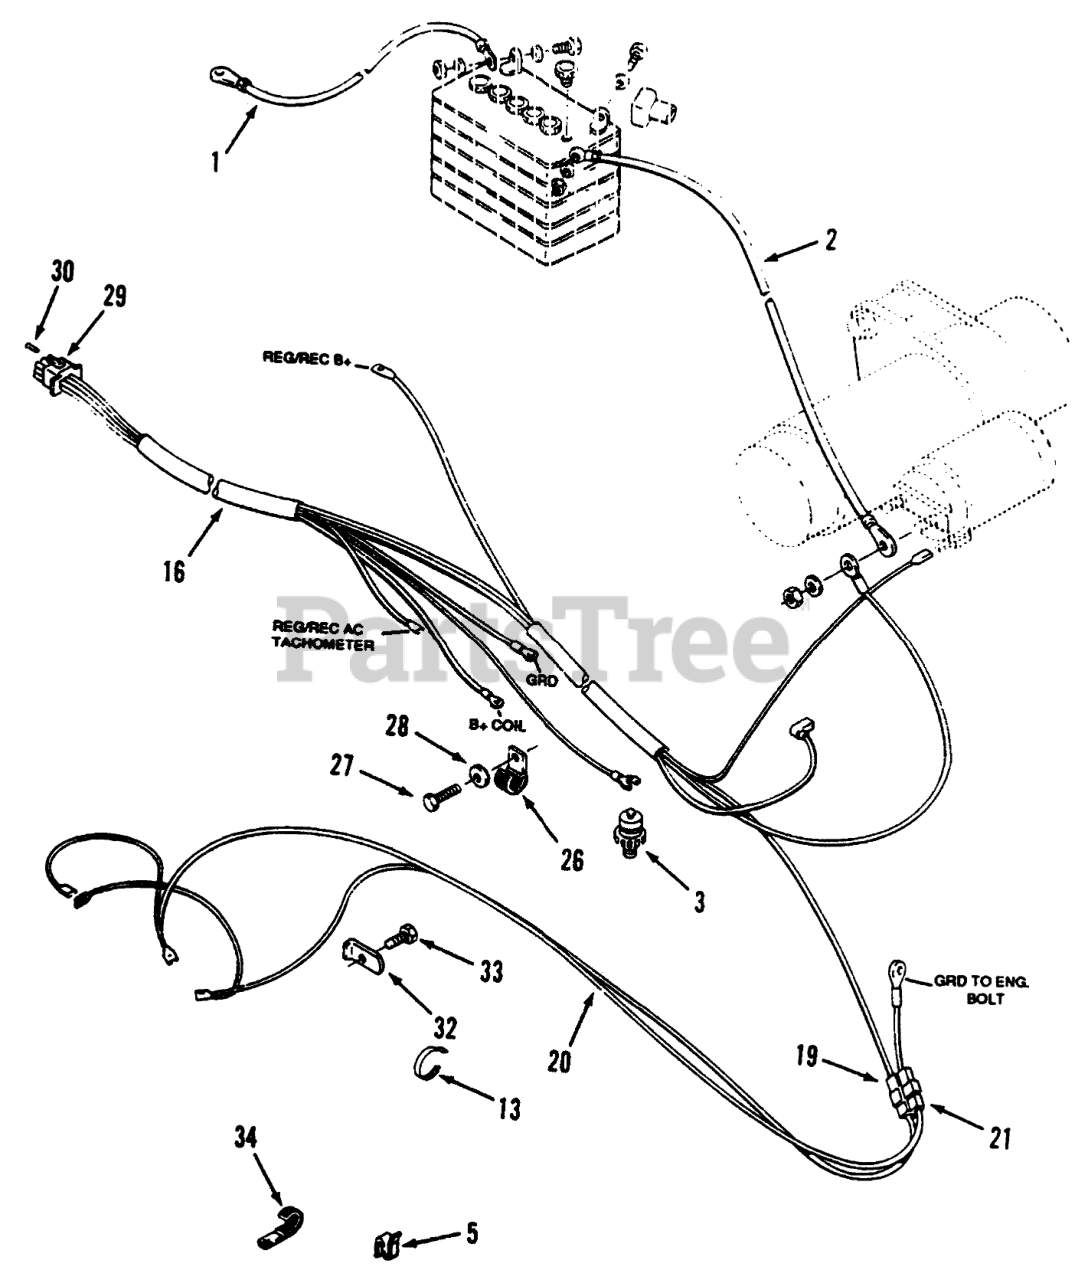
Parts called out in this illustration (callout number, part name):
1	Cable-Battery Ground
2	Cable-Battery (+) to Solenoid
3	SWITCH - OIL PRESSURE
4	Boot
5	SPEED CLIP
13	TIE-CABLE
16	HARNESS - ENGINE WIRE
19	MALE CONNECTOR
20	HARNESS-HEADLIGHT
21	CONNECTOR BODY
26	Clip
27	Bolt
28	LOCKWASHER 1/4 IT
29	CONNECTOR CAP
30	CONTACT SOCKET
32	LOCK-HEADLIGHT
33	SCREW-HWH
34	CLIP
